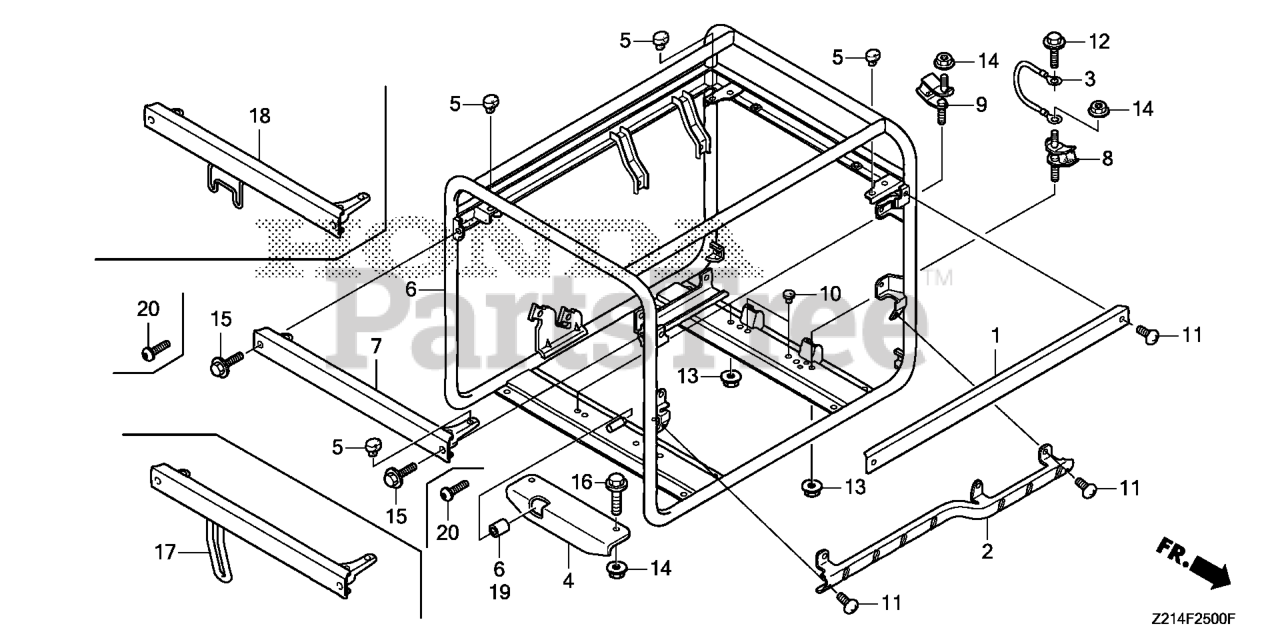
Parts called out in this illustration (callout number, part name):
3	CABLE, SUB-GROUND
4	BRACKET, STOPPER
5	RUBBER, FUEL TANK MOUNTING
6	FRAME *NH105* (MAT BLACK)
8	RUBBER (LOWER)
9	RUBBER (LOWER)
10	RUBBER, BUMP STOP
12	BOLT, GROUND (6X16) (WASHER 12.5MM) (ZN)
13	NUT, FLANGE (8MM)
14	NUT, FLANGE (10MM)
16	BOLT, FLANGE (10X40)
18	FRAME, SIDE *NH105* (MAT BLACK)
19	BOOT, COLUMN STOPPER
20	BOLT, DISK (8X16) (TORX)
